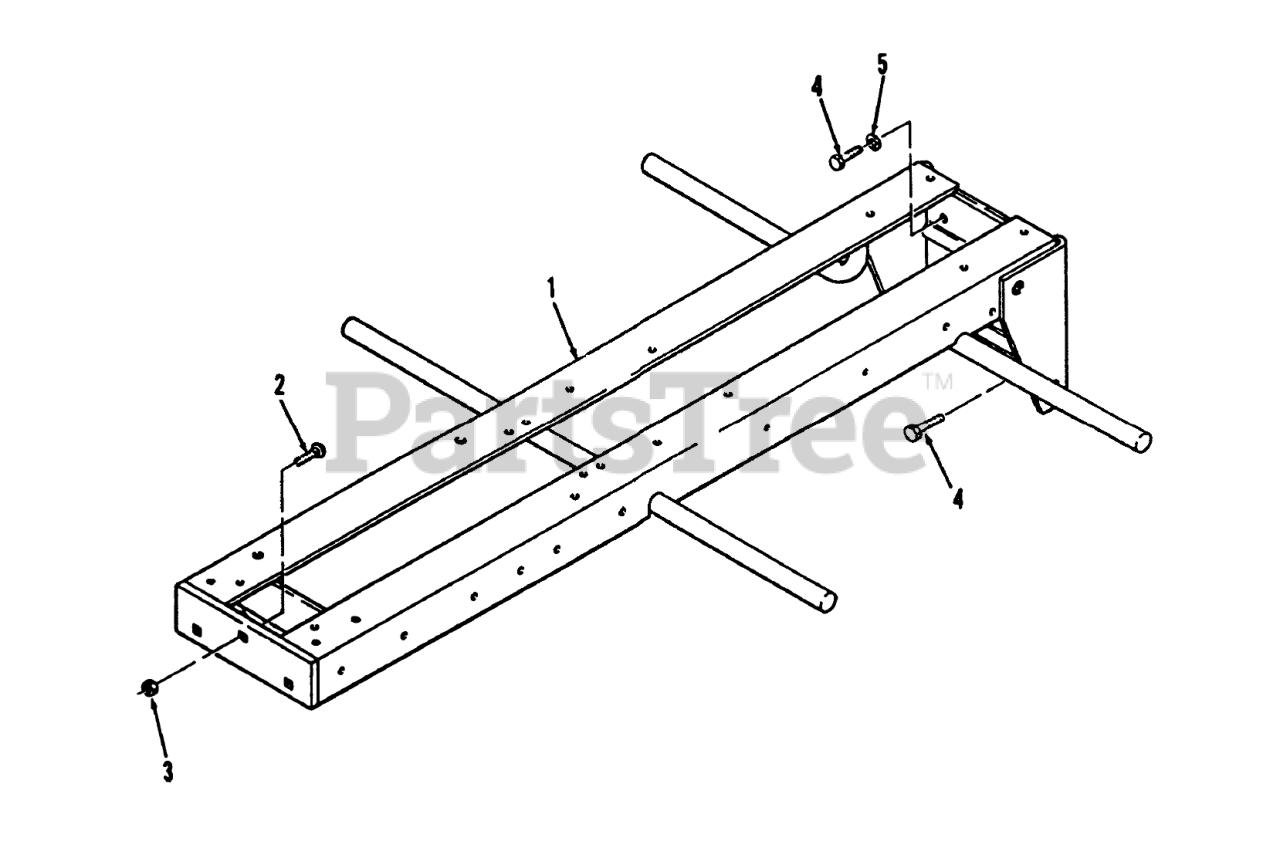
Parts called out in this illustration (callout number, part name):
1	WELD FRAME R
2	BOLT-CARR
3	NUT-LOCK, NI
4	SCREW-HH
5	WASHER-LOCK
